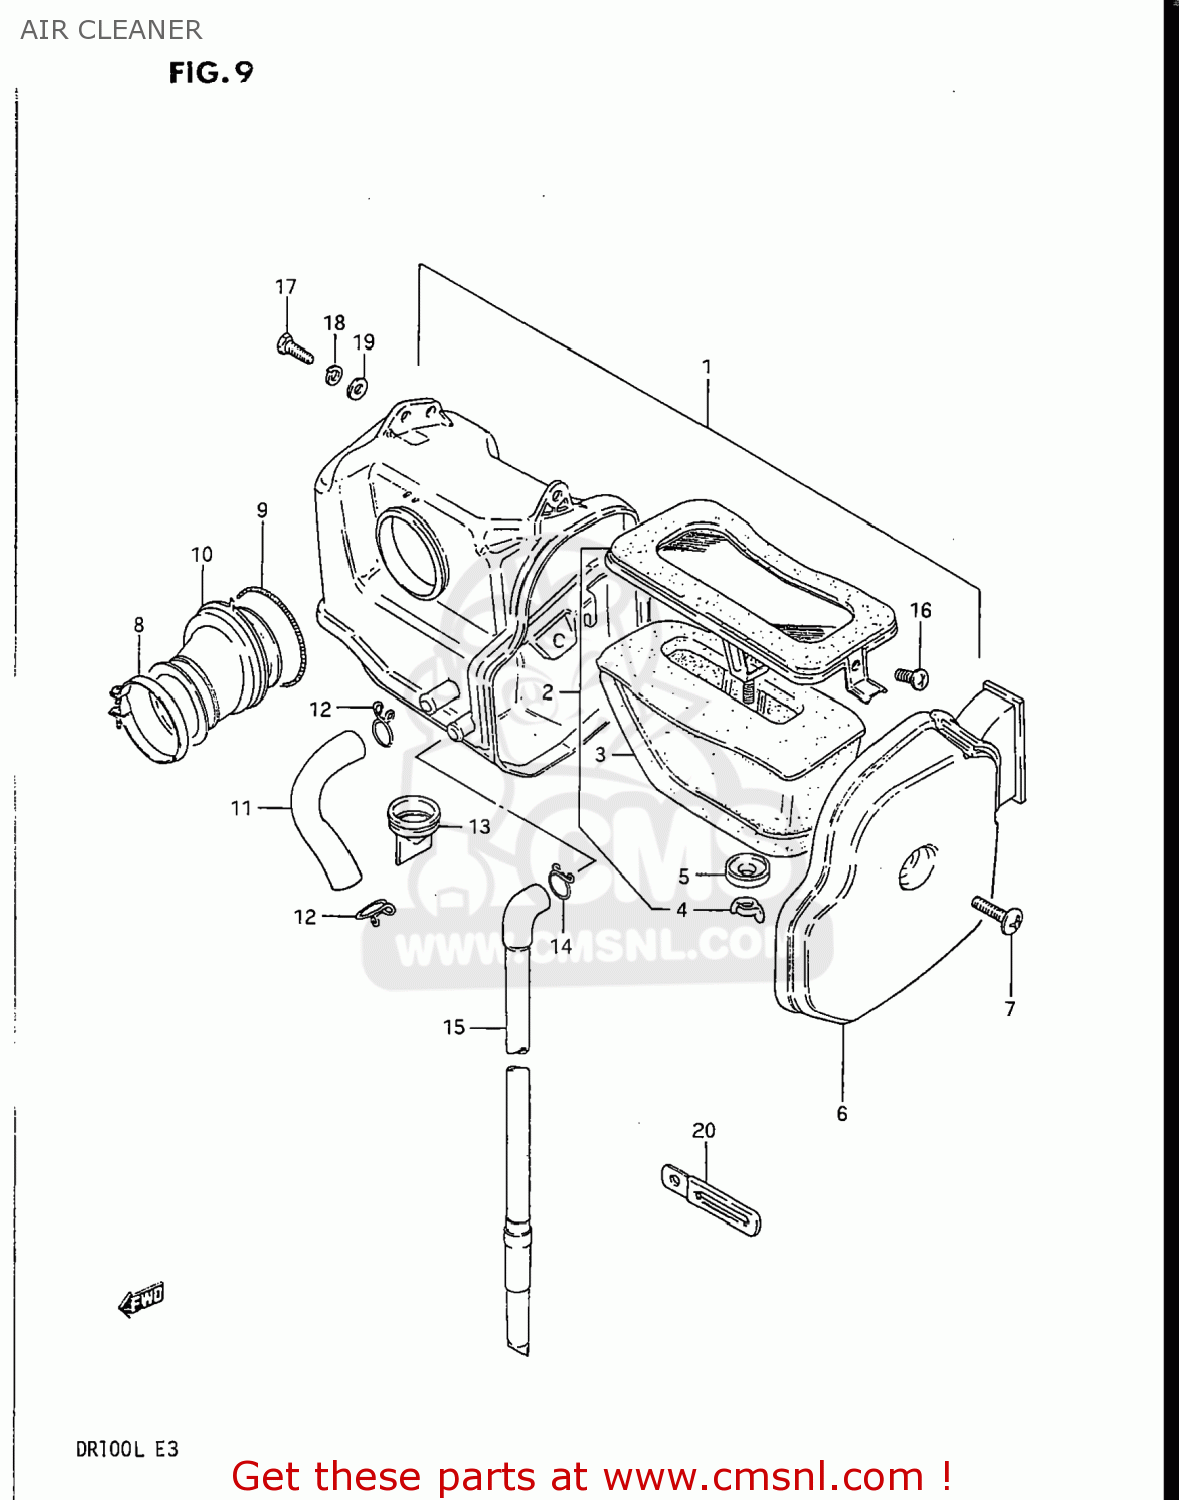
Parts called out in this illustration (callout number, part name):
1	CLEANER ASSEMBLY,AIR
2	FILTER ASSY
3	ELEMENT,AIR CLEANER
4	NUT
5	WASHER
6	CAP,AIR CLEANER
7	SCREW(6X25)
8	CLAMP
9	CLAMP,CLEANER SIDE
10	TUBE,OUTLET
11	TUBE,AIR CLEANER BREATER
12	CLAMP
13	HOSE,AIR CLEANER DRAIN
14	CLIP
15	DRAIN TUBE
16	SCREW(5X10)
17	BOLT
18	WASHER,LOCK
19	WASHER
20	CLAMP
